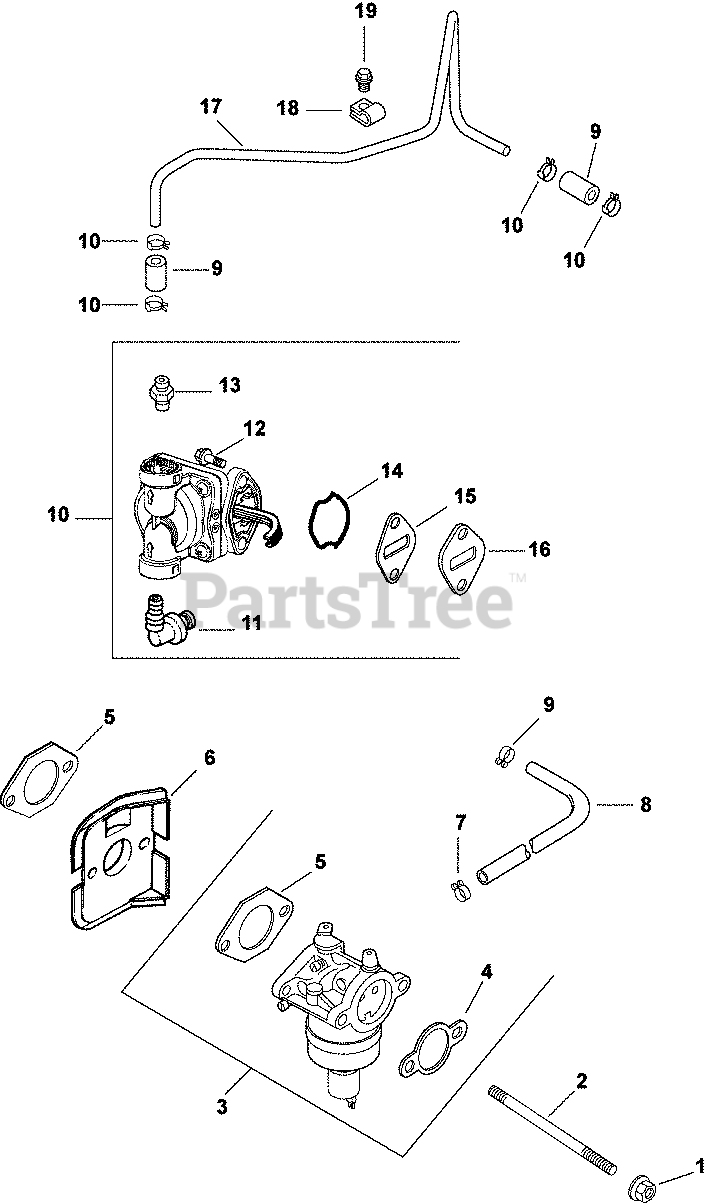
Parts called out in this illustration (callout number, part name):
1	NUT, FLG M6X1.0
2	STUD,M6X1.0X116
3	CARBURETOR W/GASEKTS - USE 12 853 139-S
4	GASKET, AIR CLEANER BASE
5	GASKET, CARBURETOR
6	DEFLECTOR, HEAT
7	CLAMP, BAND SPRING HOSE-(#2523737S)
8	HOSE,LW PERM.FUEL 24.00"-USE 25 111 81-S
9	CLAMP, HOSE (KM)-USE 25 237 31-S
10	KIT, FUEL PUMP
11	CONNECTOR, 90 DEG. HOSE
12	SCREW, LBD SKT M6x1.0x20-(#25086403S)
13	KIT, STRAIGHT FITTING
14	O-RING, FUEL PUMP
15	GASKET, FUEL PUMP
16	SPACER, FUEL PUMP
17	LINE, FUEL
18	CLIP, TUBE & WIRING (KM)
19	SCREW, FLG THD FRM M5X.8X10
